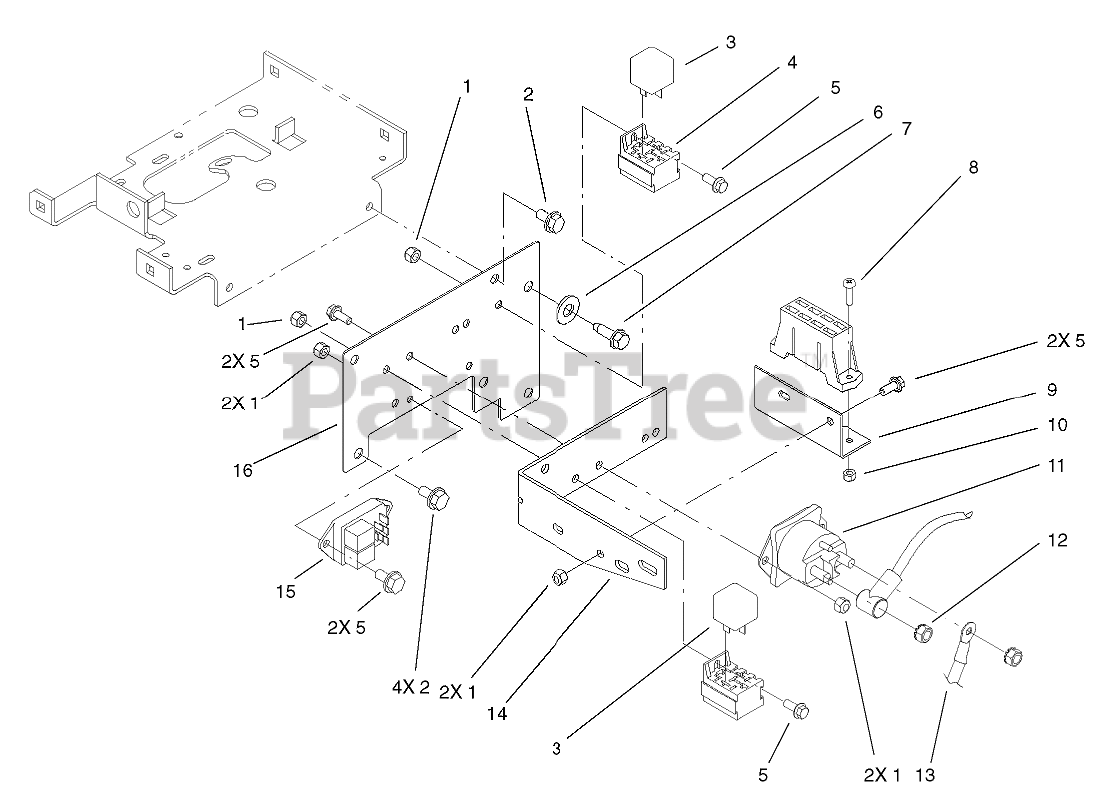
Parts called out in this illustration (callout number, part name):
1	NUT-LOCK, NI
2	SCREW-HWHTF
3	RELAY
4	HARNESS-WIRE
5	SCREW-HHF
6	WASHER-FLAT
7	SCREW-TAPTITE
8	SCREW-PAN
9	FUSE HOLDER
10	NUT-LOCK, NI
11	SOLENOID
12	NUT-KEPS
13	CABLE-BATTERY, POSITIVE
14	BRACKET-BELT
15	MODULE-CLUTCH
16	PLATE-HOODSTAND, FRONT
